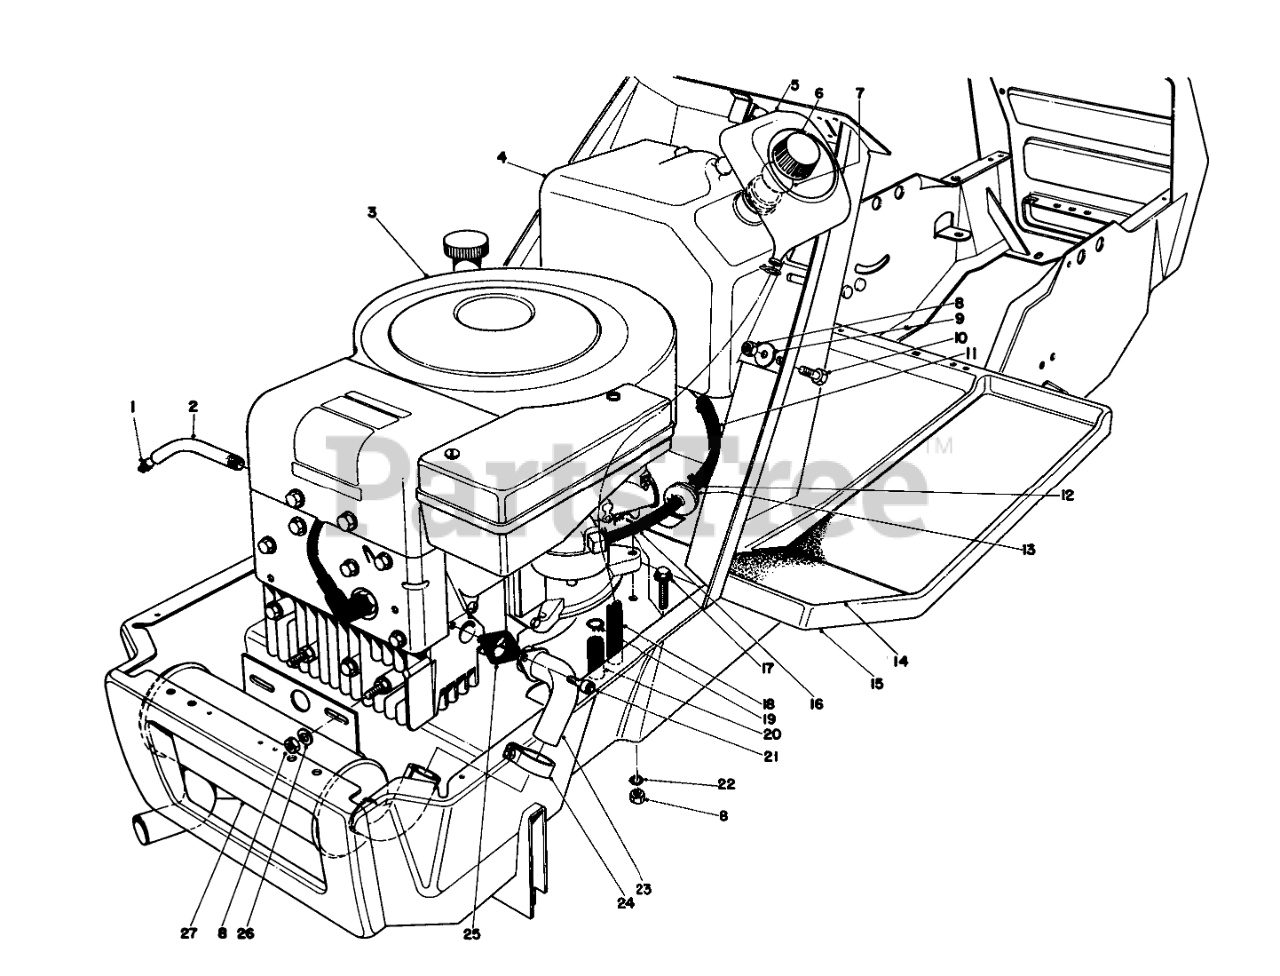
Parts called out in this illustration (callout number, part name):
1	PLUG-PIPE, SQH
2	OIL DRAIN TUBE
3	Engine
4	Gas Tank (Incl. Ref. #5)
5	Funnel-Overflow
6	Gas Cap (Incl. Ref. #7)
7	Gasket Gas Cap
8	NUT-LOCK, CONE
9	WASHER
10	SCREW-HH
11	GAS HOSE
12	Clamp
13	Nut
14	LH FOOT TREAD
15	Frame
16	GAS HOSE
17	SCREW-HH
18	FUNNEL HOSE
19	HOSE CLAMP
20	CARB DRAIN HOSE
21	SCREW-HSH
22	WASHER-LOCK, INTERNAL
23	Exhaust Pipe
24	MUFFLER CLAMP
25	Exhaust Gasket
26	WASHER-PLAIN
27	MUFFLER
